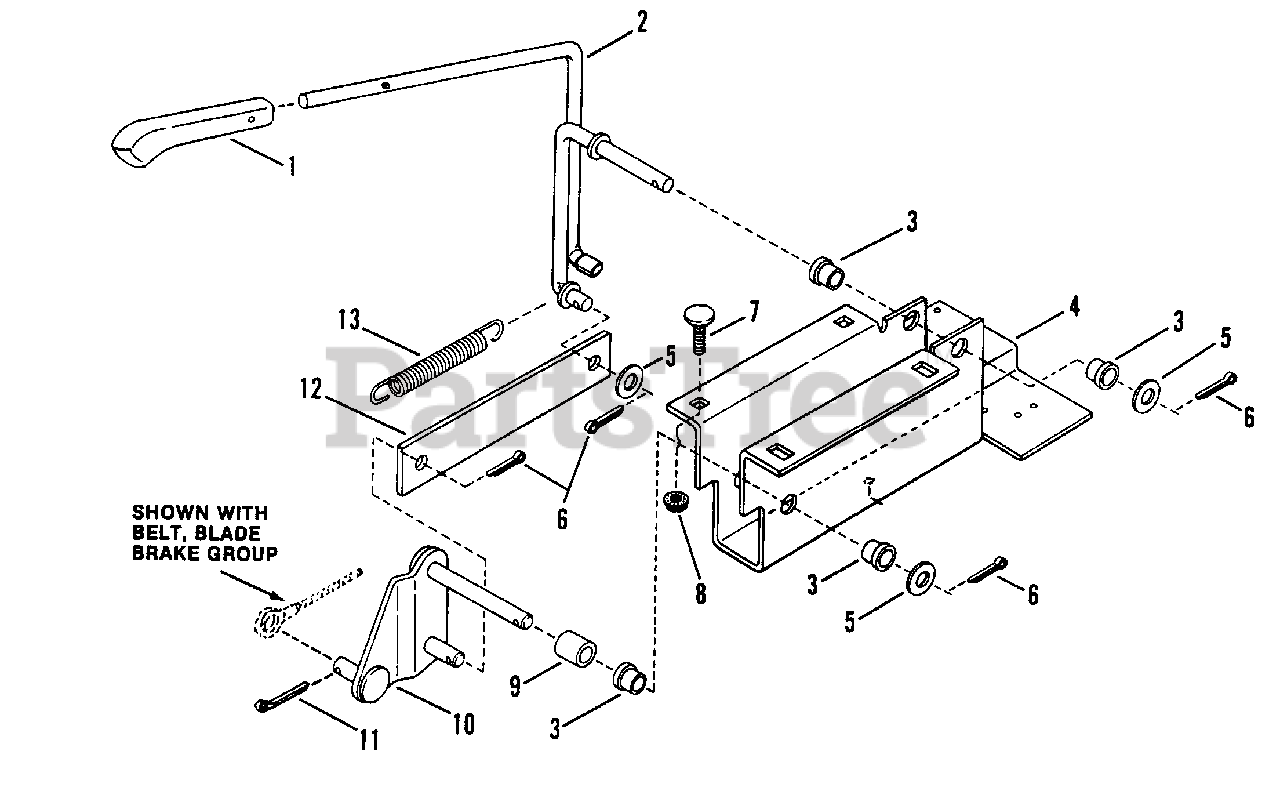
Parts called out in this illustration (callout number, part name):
1	KNOB, Handle
3	BUSHING
4	BRACKET, Handle
5	WASHER
6	COTTER-PIN, 3/32 x 3/4"
7	BOLT, 1/4-20 x 5/8" Flat Head Carriage
8	NUT, 1/4-20 Hex Flange Lock
9	SPACER
10	PIVOT ARM ASSEMBLY
11	COTTER-PIN, 3/32 x 1"
13	SPRING, Return
